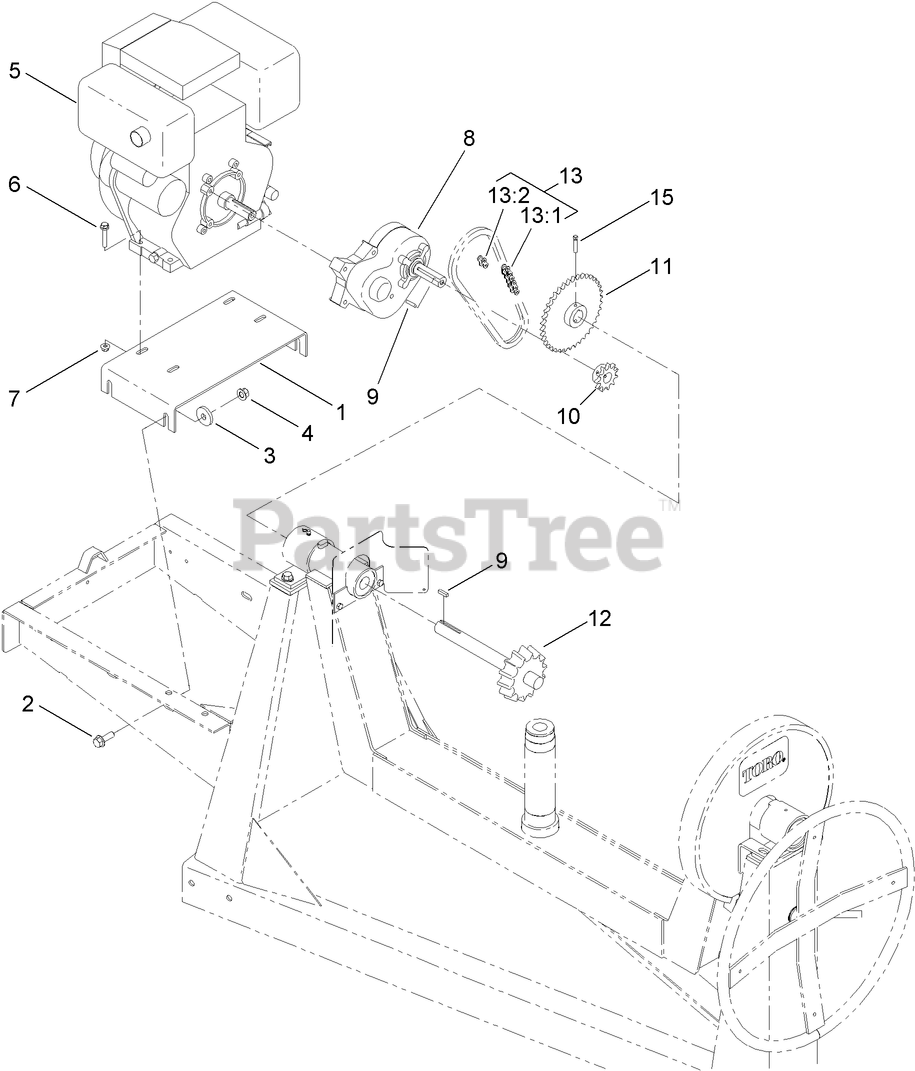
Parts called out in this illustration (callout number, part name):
1	BASE-MOTOR
2	SCREW-HHF
3	WASHER-FLAT
4	NUT-LOCK
5	ENGINE-DIESEL
6	SCREW-HHF
7	NUT-HF, NI
8	REDUCER-GEAR
10	SPROCKET
11	SPROCKET
12	SHAFT-DRIVE
13	CHAIN SET
13:1	CHAIN
13:2	LINK-CONNECTING, NO. 50
15	SCREW-SET
